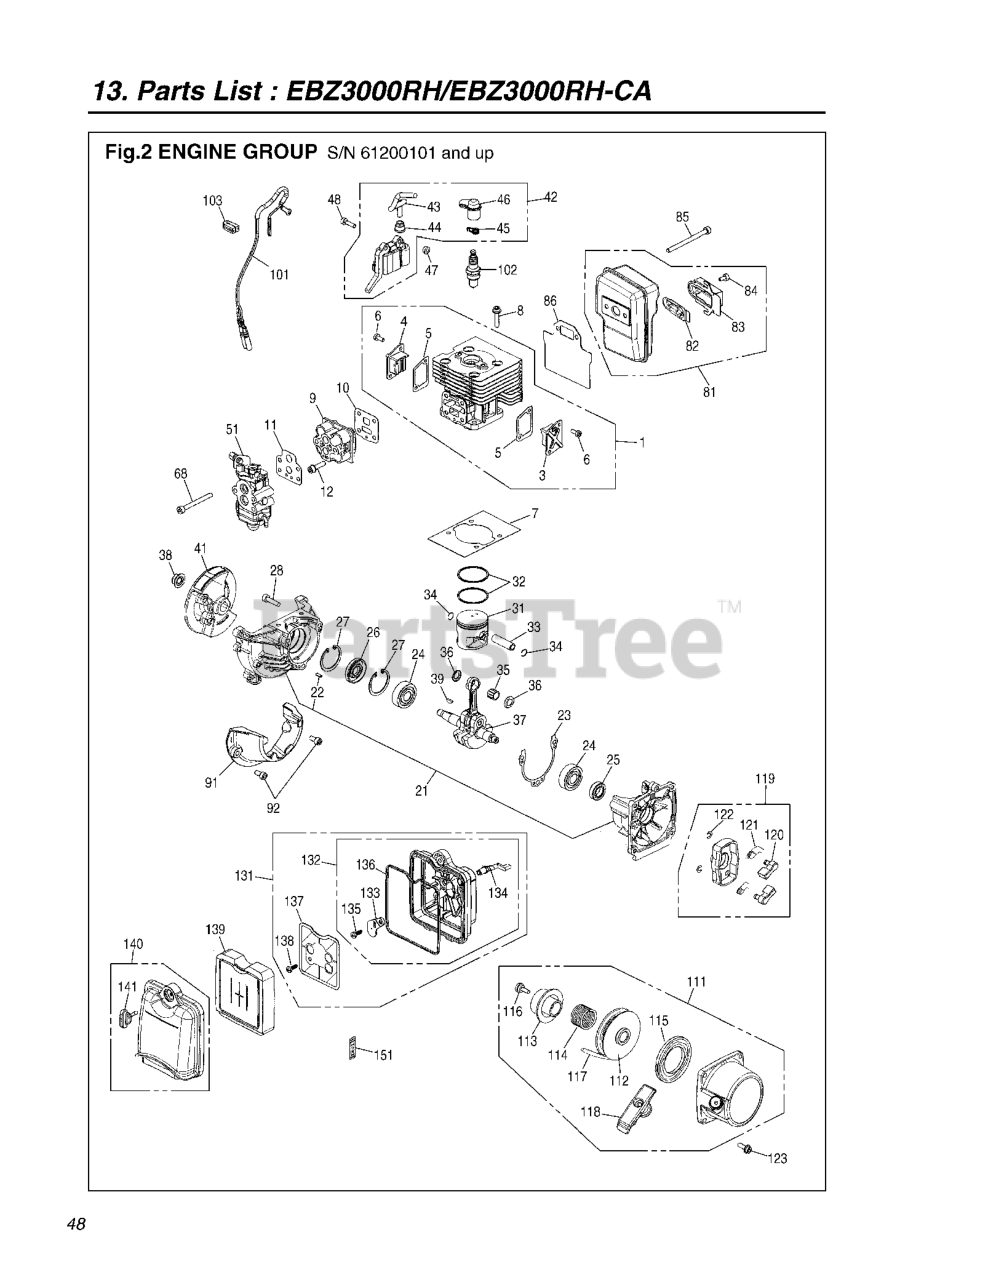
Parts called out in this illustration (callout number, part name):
1	CYLINDER
3	COVER TR(S)
4	COVER TR (F)
5	GASKET TR
6	BOLT
7	GASKET BASE
8	BOLT
9	INSULATOR
10	GASKET INSULATOR
21	CRANKCASE-C
22	PIN
23	GASKET CASE
24	BEARING
31	PISTON
32	RING
33	PIN
37	CRANKSHAFT C
38	NUT
39	KEY
42	COIL-A
44	CAP
47	SPACER
51	CARBURETOR A
81	MUFFLER A
82	ARRESTER
83	EXHAUSE DUCT
85	BOLT
102	PLUG CMR7H
111	RECOIL-A
113	PLATE, CAM
114	SPRING, DAMPER
115	SPRING,SPIRAL
119	PULLEY-A
122	E-RING
131	BODY & SCREEN
132	BODY-A (RPLS 848F028310)
133	PLATE.CHOKE
134	LEVER CHOKE
135	SCREW
138	SCREW
139	ELEMENT
140	AIR FILTER COVER
151	LABEL, CHOKE
